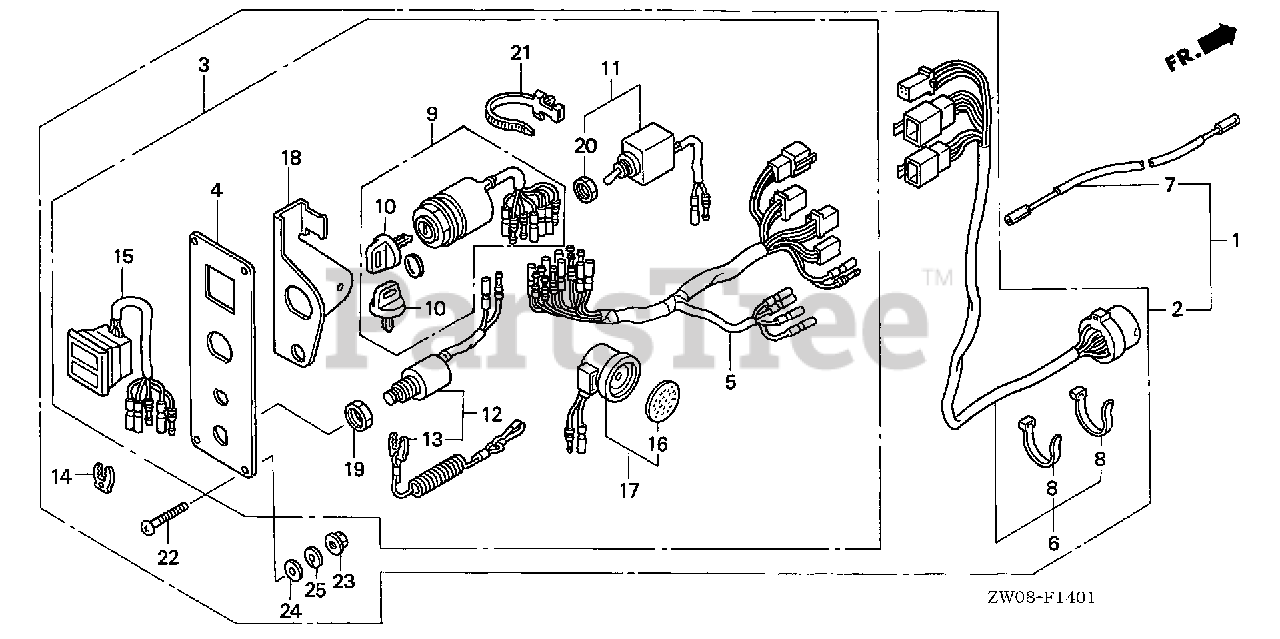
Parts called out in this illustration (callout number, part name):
1	PANEL KIT, SWITCH (DUAL)
2	PANEL KIT, SWITCH (DUAL)
3	PANEL ASSY., CONTROL
4	PANEL, CONTROL FOR DUAL: QTY = (2)
4	PANEL, CONTROL
5	HARNESS ASSY., SWITCH PANEL
6	CABLE ASSY., SWITCH PANEL Use up to Frame SN 1300359.
6	CABLE ASSY., SWITCH PANEL
6	CABLE ASSY., SWITCH PANEL Use from Frame SN 1300360.
7	WIRE ASSY., GROUND (BONDING) Use up to Frame SN 1300354.
8	TIE, CABLE (NATURAL 2.4X92) Use up to Frame SN 1300359.
9	SWITCH ASSY., COMBINATION DUAL QTY = (2) (SINGLE)
10	KEY ASSY., COMBINATION SWITCH (35100-ZV5-003 ONLY) DUAL QTY = (4) (SINGLE)
11	SWITCH ASSY., SOLENOID
12	SWITCH ASSY., EMERGENCY STOP
13	WIRE, EMERGENCY (SINGLE) (DUAL)
14	CLIP, EMERGENCY LOCK
15	LAMP ASSY., INDICATION (2-LED) DUAL QTY = (2) (SINGLE)
16	PLATE, TURN SIGNAL BUZZER DUAL QTY = (2) (SINGLE)
17	BUZZER, WARNING DUAL QTY = (2) (SINGLE)
18	BRACKET, BUZZER DUAL QTY = (2) (SINGLE)
19	NUT, HEX. (16MM) DUAL QTY = (2) (SINGLE)
20	NUT, HEX. (12MM)
21	BAND, WIRE HARNESS (150MM) (NATURAL) DUAL QTY = (2) (SINGLE)
22	SCREW, PAN (5X40)
23	NUT, FLANGE (5MM)
24	WASHER, PLAIN (5MM)
25	WASHER, SPRING (5MM) DUAL QTY = (8) (SINGLE)
